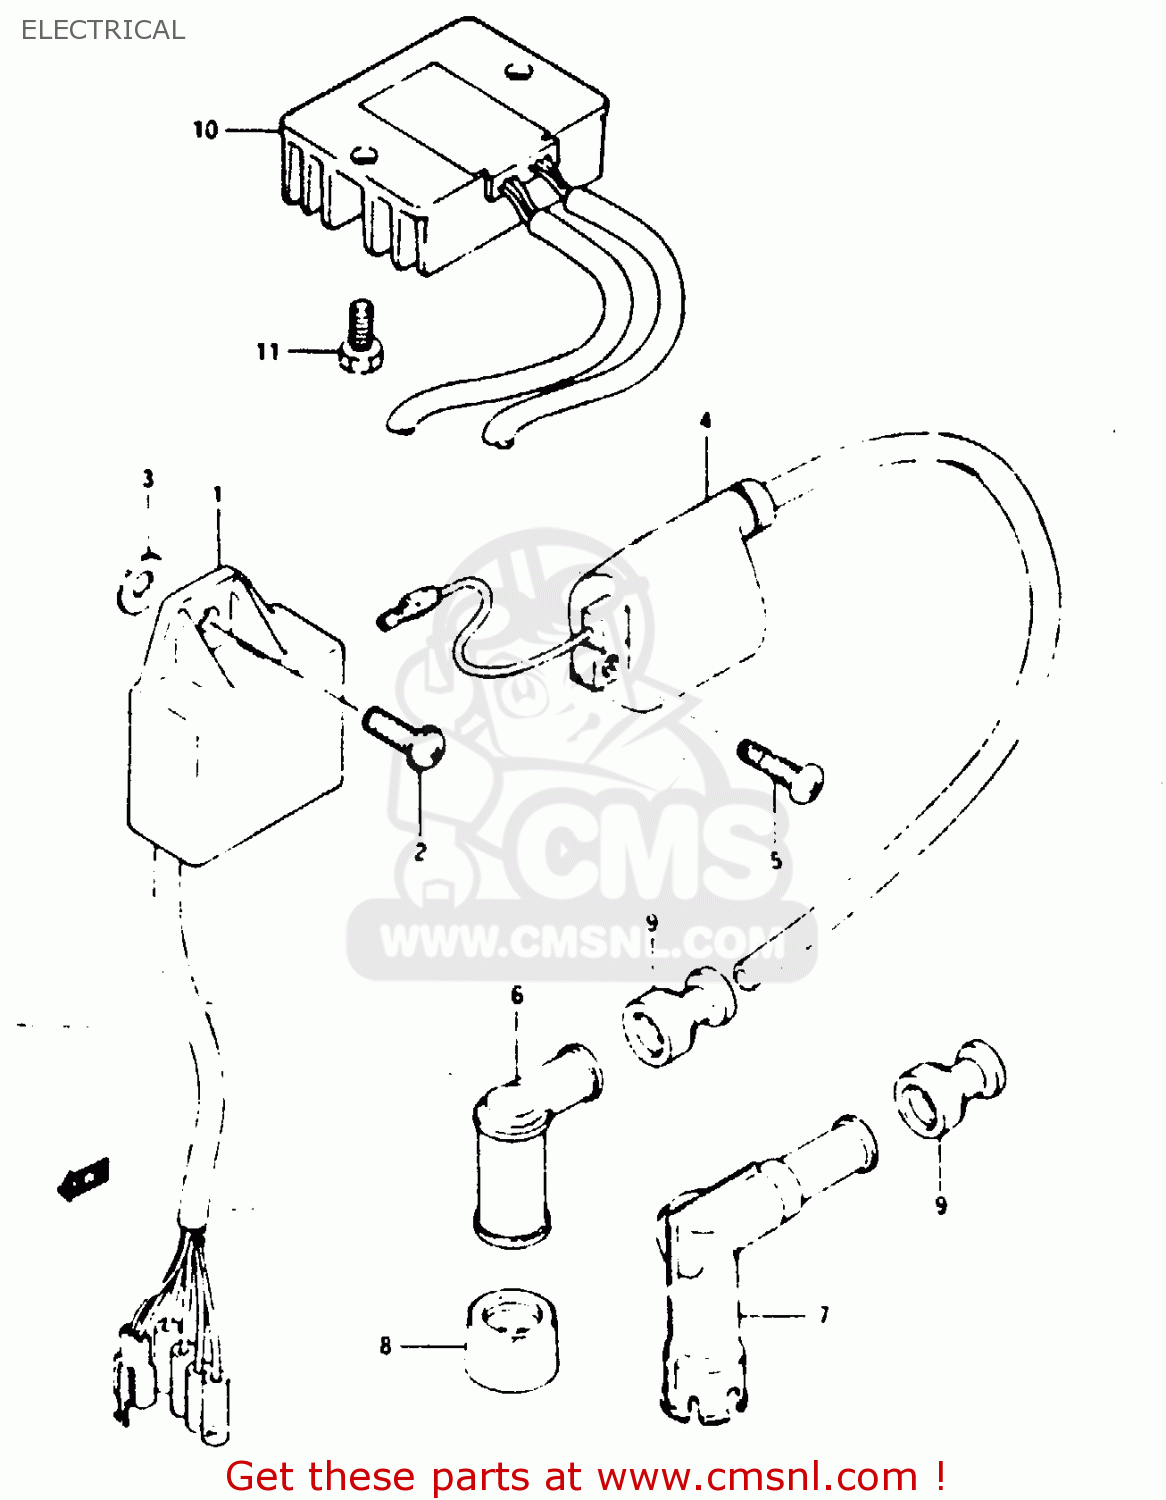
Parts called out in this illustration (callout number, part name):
1	C.D.I UNIT
2	SCREW
3	WASHER
4	COIL ASSY, IGNITION
5	SCREW(6X21)
7	CAP,SPARK PLUG
9	SEAL,SPARK PLU
10	RECTIFIER ASSY
11	SCREW
